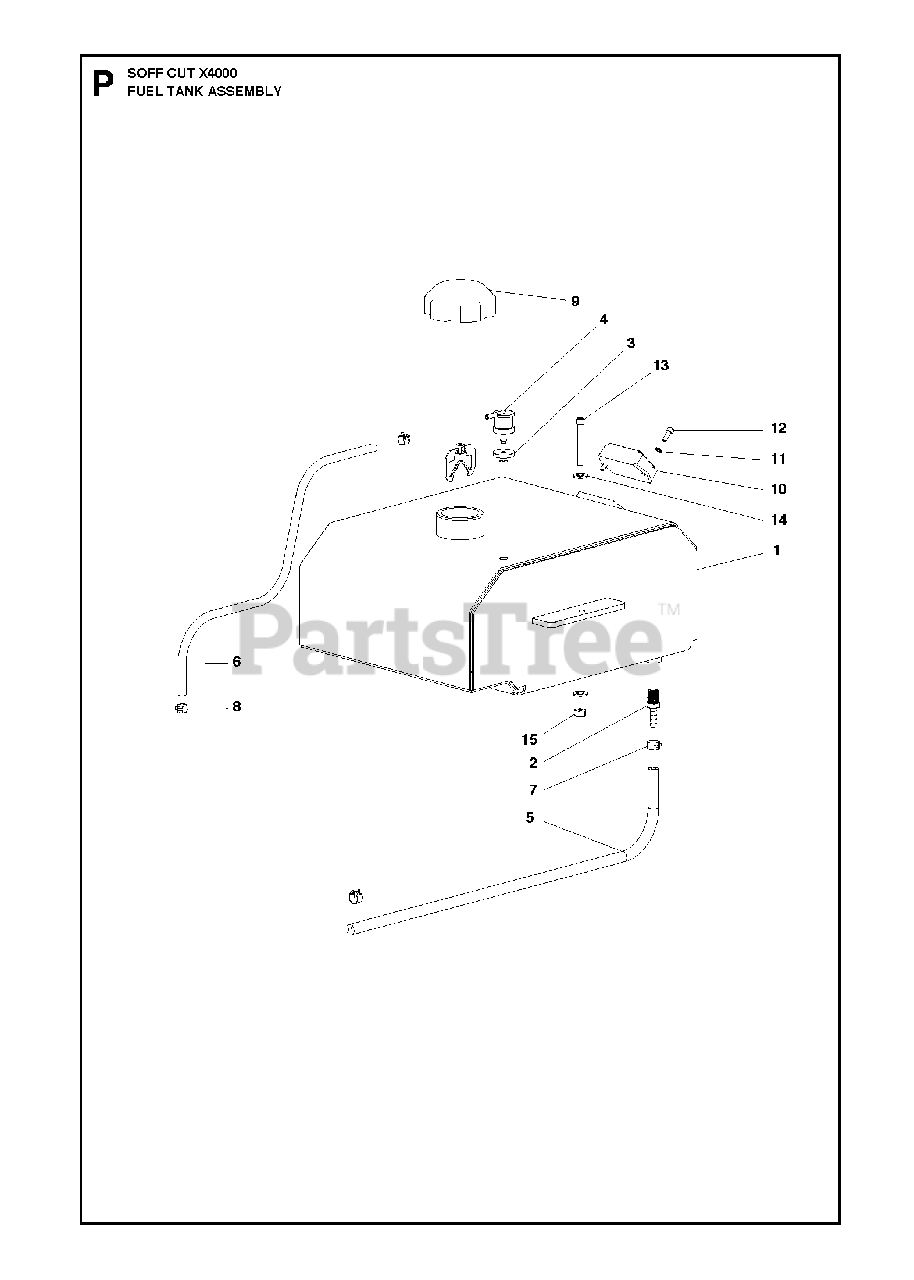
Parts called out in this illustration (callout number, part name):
3	GROMMET
14	FLAT WASH 1/4 PFC9 SAE ZINC
15	NUT
